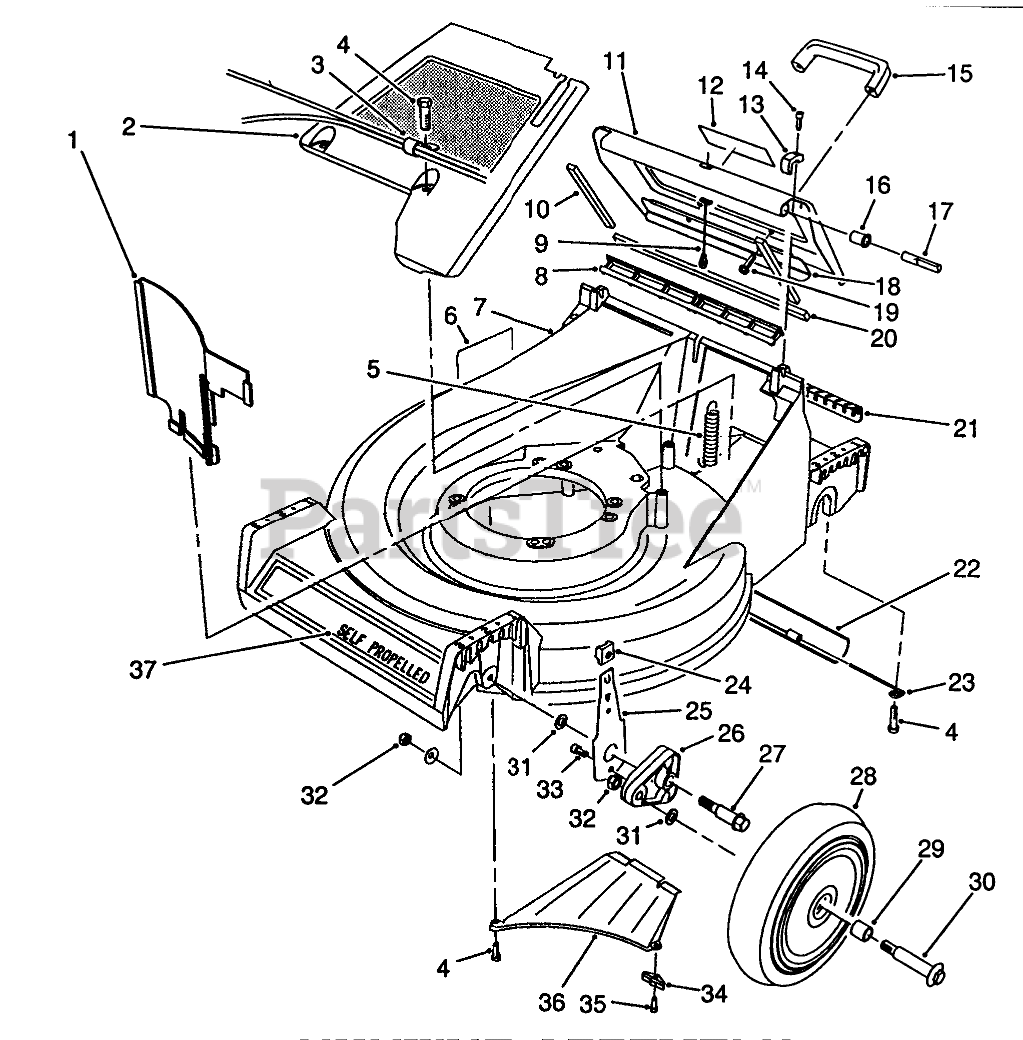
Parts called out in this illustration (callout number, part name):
1	PANEL-VERTICAL
2	PaneI-Screen
3	CLAMP
4	SCREW-HWHTF
5	EXTENSION-SPRING
6	DECAL-DANGER
7	21" Housing Assembly (Incl. Ref. #6)
8	DOOR SEAL
9	DOOR CABLE
10	DOOR SIDE SEAL
11	Door-Discharge (Incl. Ref. #10, 12, 18 & 20)
12	DECAL - WARNING
13	HINGE CLAMP
14	SCREW-HSH
15	HANDLE-DOOR
16	DOOR BUSHING
17	HINGE PIN
18	DOOR - BRACE
19	SCREW-HWH
20	DOOR END SEAL
21	ACCESS COVER
22	TRAILING SHIELD
23	LH SHIELD HANGER
24	KNOB-ARM
25	FRONT SPRING ARM ASM
26	ARM-PIVOT, FRONT
27	BOLT-SHOULDER
28	Wheel & Tire Assembly (Incl. Ref. #29)
29	BUSHING
30	WHEEL BOLT
31	WASHER
32	Nut
33	SCREW-HSH, THREAD FORMING
34	Bracket-Discharge
35	SCREW-HWHTF
36	Ramp Discharge
37	DECAL - 21 SP
